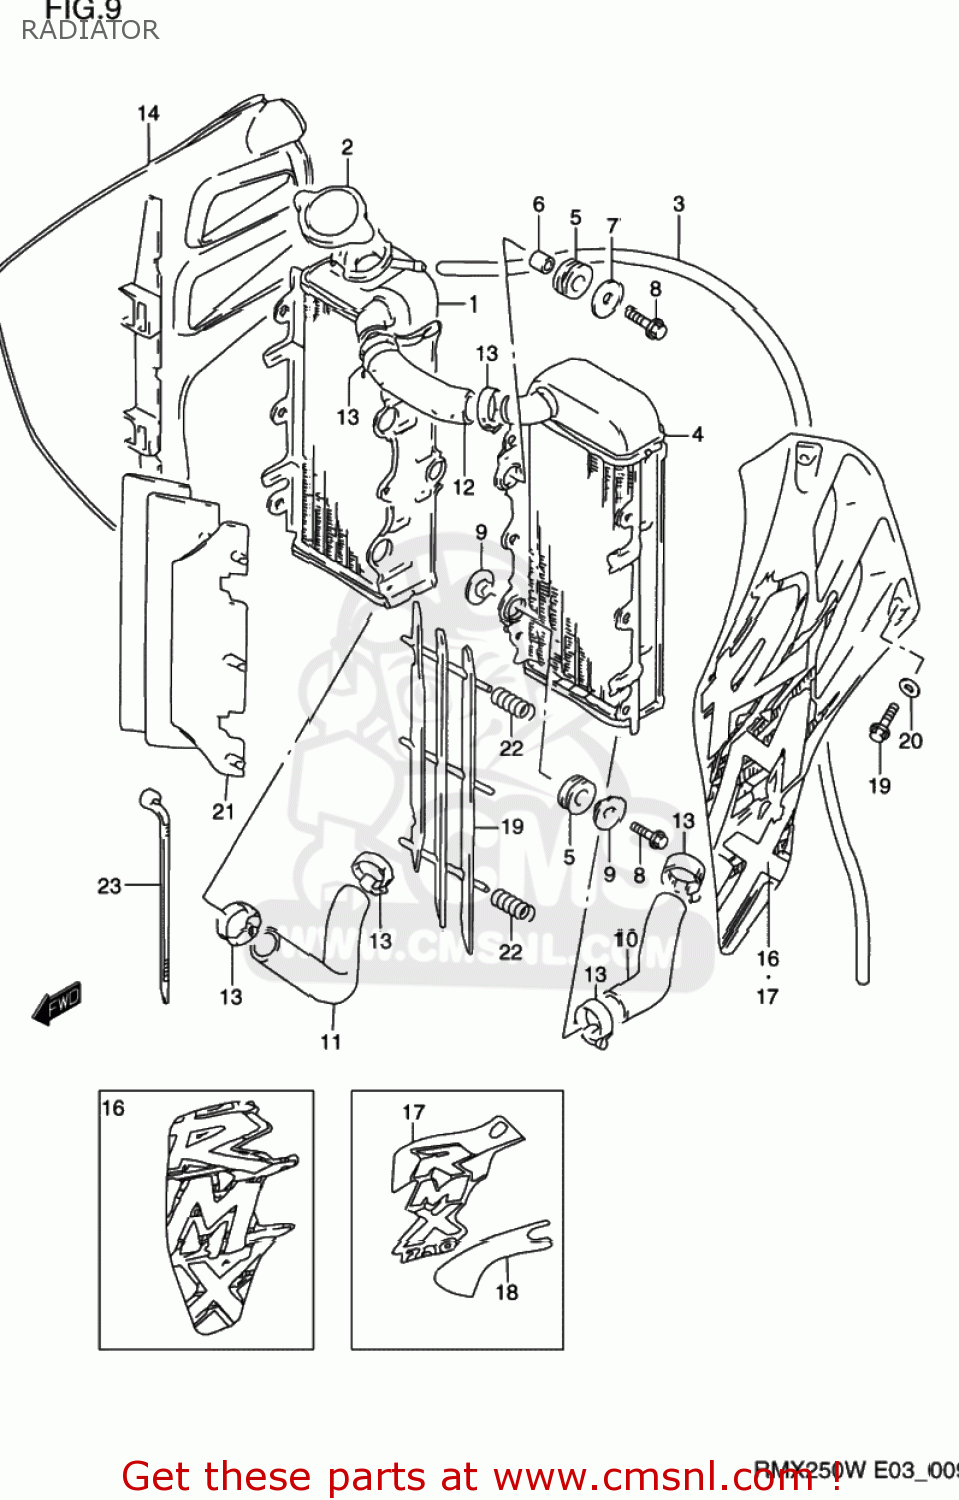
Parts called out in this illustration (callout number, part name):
1	RADIATOR,WATER,R
2	CAP,RADIATOR
3	HOSE(5X8X2000)
4	RADIATOR COMP,WATER,LEFT
5	CUSHION,RADIATOR LWR
6	SPACER(6.5X10.5X12)
7	WASHER(6.5X24X1.2)
8	SCREW
9	WASHER,RDTR SPRT
10	HOSE,RADIATOR INLET
11	HOSE,RADIATOR OUTLET
12	HOSE,RADIATOR INLET
13	CLAMP
14	COVER,RADIATOR,R
15	COVER,RADIATOR,L
16	TAPE,RADIATOR COVER,LEFT
17	EMBLEM,RADIATOR COVER
18	TAPE,RADIATOR COVER,LEFT
19	BOLT
20	WASHER
21	LOUVER,RADIATOR
22	SPRING
23	CLAMP L:165
